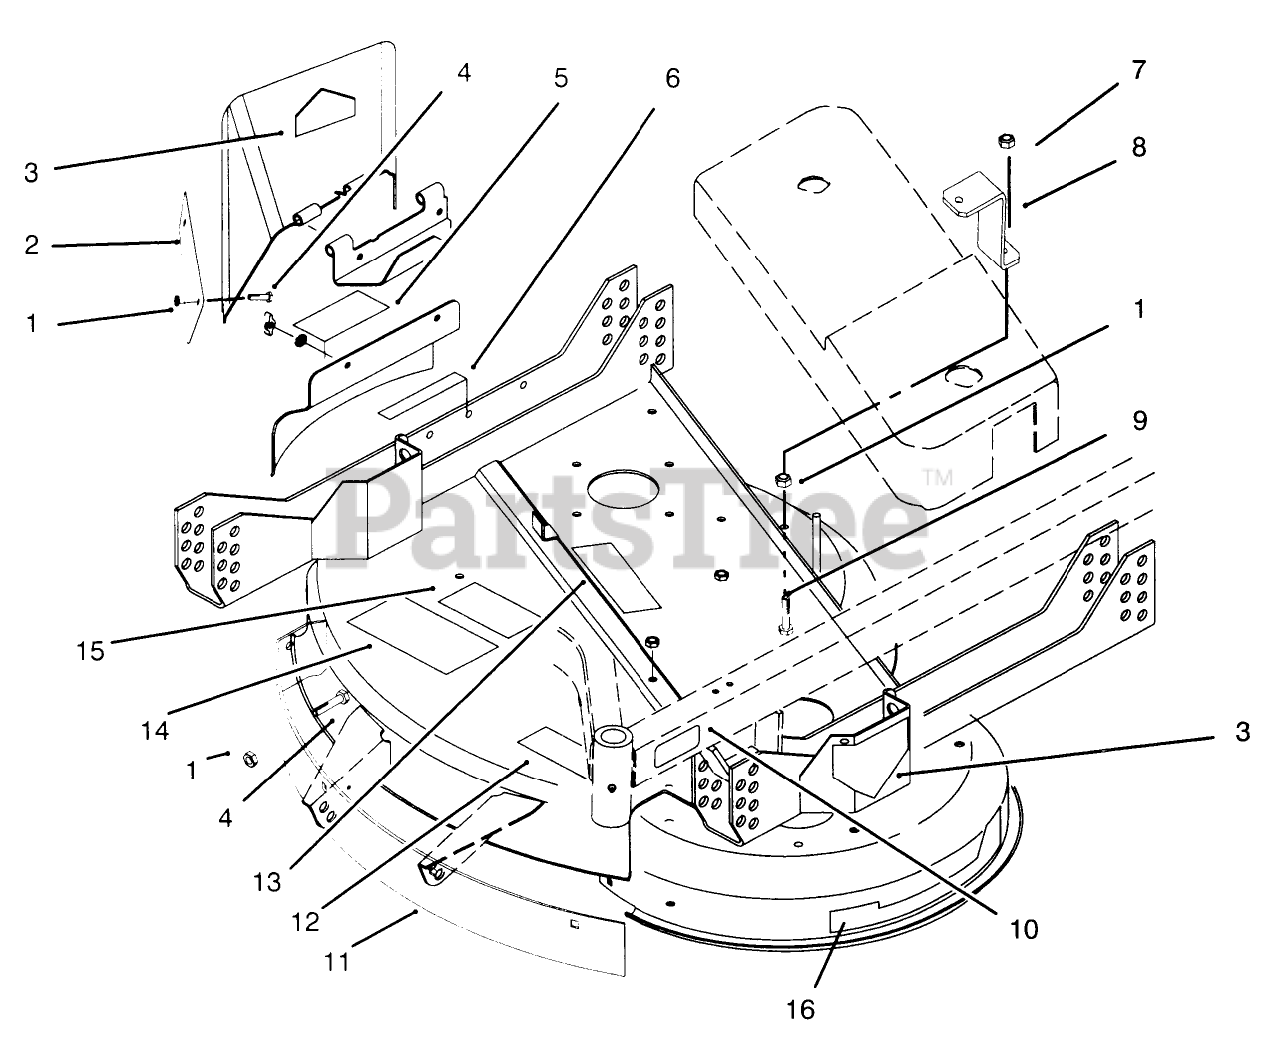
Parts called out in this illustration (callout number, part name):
1	NUT-LOCK, NI
2	Baffle-Deflector
3	DECAL-DANGER
4	SCREW-HH
5	Decal-Danger
6	DECAL - WARNING
7	NUT-HEX
8	BRACKET-DECK, BELT GUARD
9	SCREW-HH
10	DECAL-HOC
11	Baffle-Front
12	DECAL - DISCHARGE DOOR
13	DECAL-DANGER
14	DECAL-HEIGHT OF CUT
15	DECAL-TORQUE, BLADE BOLT
16	DECAL - 37"
